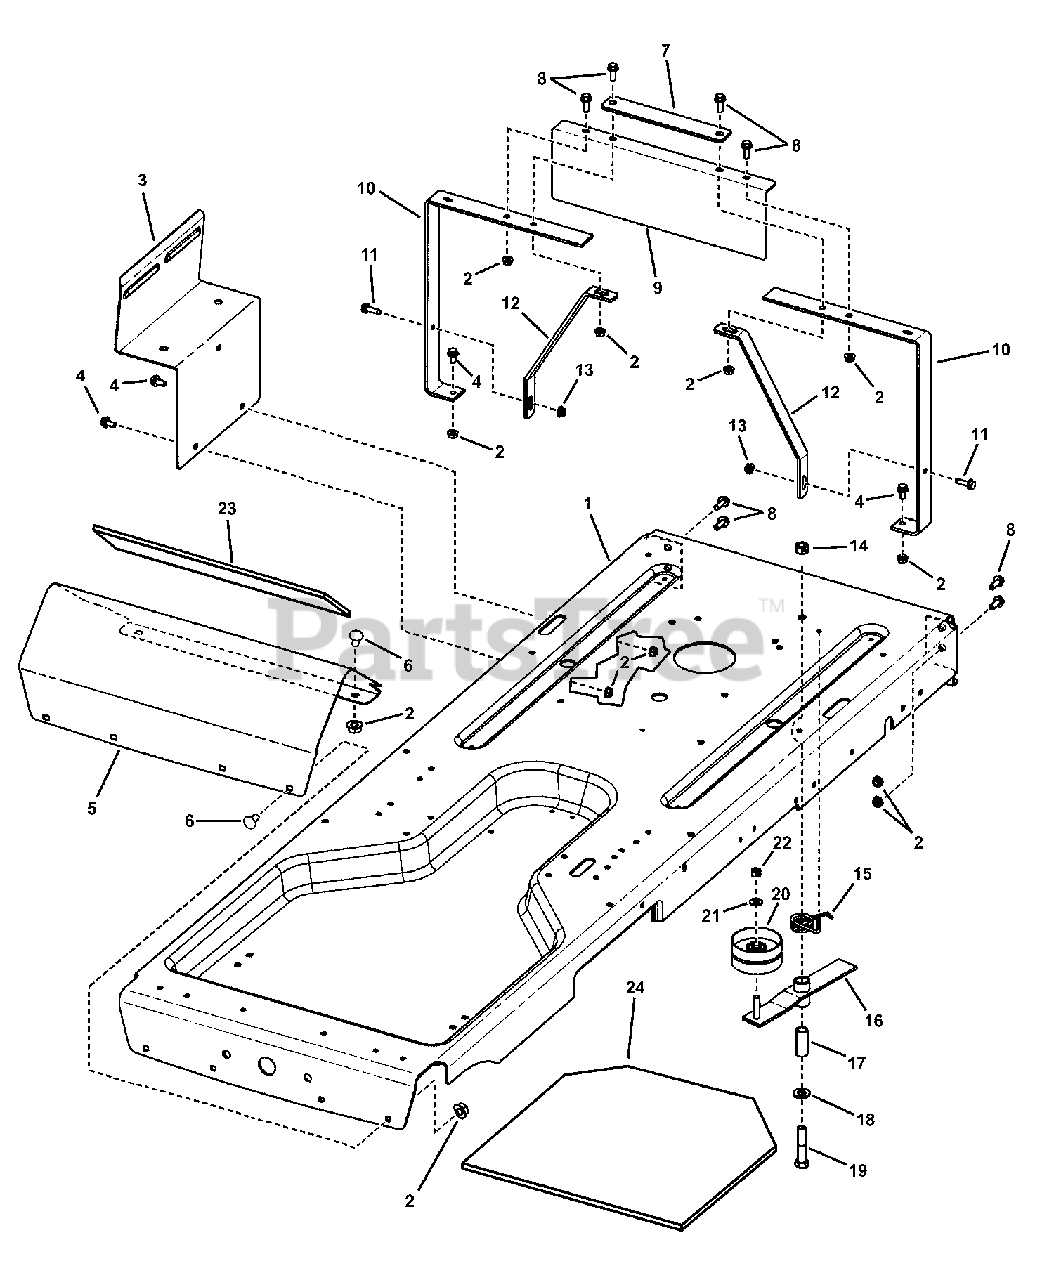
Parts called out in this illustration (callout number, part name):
1	FRAME, RZT (Cardinal Red)
2	NUT, 5/16-18 Hex Flange Lock, GR 5
3	TANK BRACKET
4	BOLT, 5/16-18 x 5/8" Hex Flange Lock, GR 5
5	FOOTREST, Snapper (Cardinal Red)
6	BOLT, 5/16-18 x 3/4" Short Neck Carriage, GR 5
7	PLATE, Rear Seat Guard
8	BOLT, 5/16-18 x 7/8" Hex Flange Lock, YZ
9	HEAT SHIELD
10	BRACKET, Body Support
11	SCREW, 5/16-18 x 1" Hex Washer Self-Tap, GR 5
12	BRACE, Hood/Fender
13	NUT, 5/16-18 Hex Flange Lock, GR 5
14	NUT, 1/2-13 Hex Center Lock, GR 5, YZ
15	SPRING, Torsion, RH Wind
16	WELDMENT, Hydro Idler
17	SPACER, Hydro Idler
18	WASHER, .531 x 1.062 x .121 Flat, YZ
19	SCREW 1/2-13 x 2-1/2" Hex Head Cap, GR 5 (Black Phosphate)
20	IDLER, 3.25" OD x .391 ID x 1.63 Backside
21	WASHER, 3/8" Flat SAE
22	NUT, 3/8-16 Hex Center Lock, GR 5 or B, YZ
23	MAT, Foot Rest RZT
24	MAT, Floor Pan
